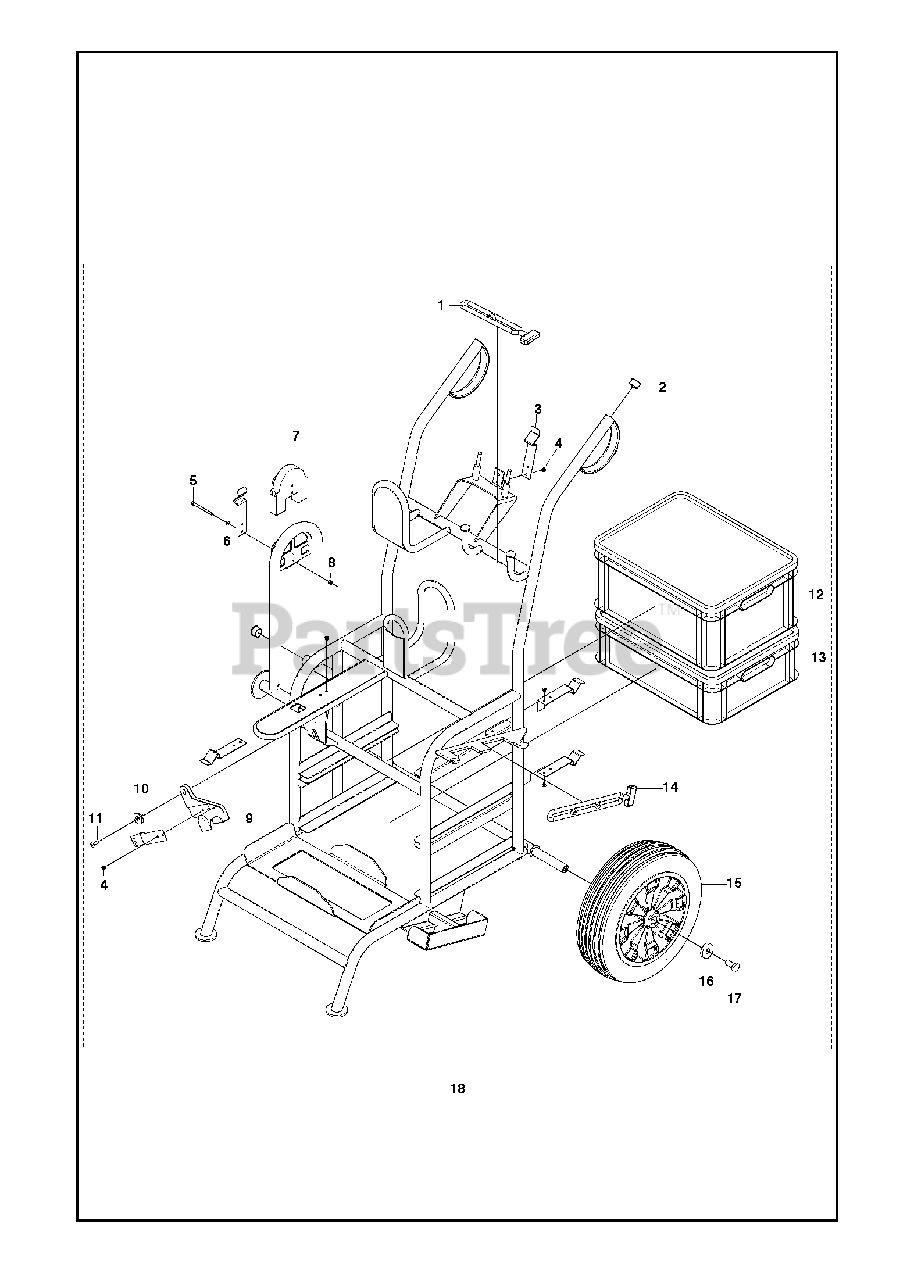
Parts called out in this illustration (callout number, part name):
6	WASHER
8	HEXAGON LOCKING NUT
12	BOXOrange box from serial number 20143700001
13	BOXOrange box from serial number 20143700001
